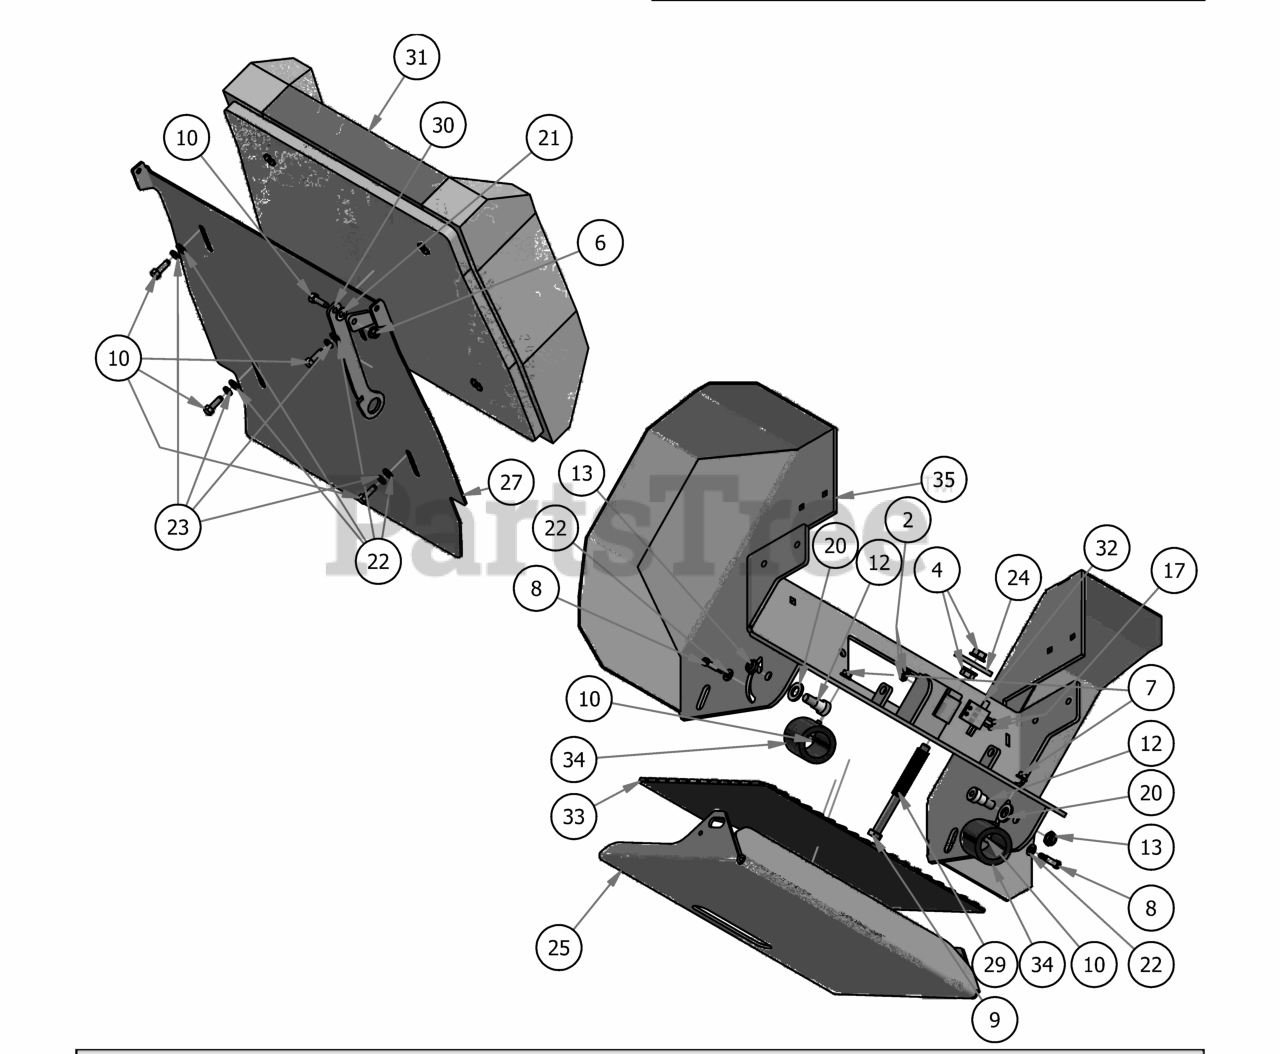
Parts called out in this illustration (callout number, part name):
1	3326 Wellnut (1/4-20 x 5/18")
2	10-24 Nylon Insert Locknut Zinc Orange Nylon
3	3/8" Nylock Flange Nut
4	1/2" Flange Nut
5	3/8" Hex Nut
6	5/16" Nylon Flange Nut
7	5/16" Flange Nut
8	5/16" x 7/8" Socket Head Shoulder Bolt
9	1/2-13 x 6 UNC
10	5/16-18 x 1 GR 5 Hex Bolt Zinc
11	3/8"-16 x 2" Gr 5 Hex Bolt
12	5/8'' x 5/8'' Shoulder Bolt
13	1/2" Nylcock Nut (1/2 Jam)
14	5/16" x 1 1/4" Carriage Bolt
15	3/8" x 1 1/4" Hex Bolt
16	3/8" x 1 1/4" Carriage Bolt
17	10-24 X 5/8 BS Button Head Bolt
18	.390 x .750 x .062 Nylon Washer
19	3/8" Lock Washer
20	.630 ID Plastic Washer
21	.360 ID Plastic Washer
22	5/16" Flat Washer
23	5/16" Lock Washer
24	MZ Deck Idler Spacer
25	2019 Stand-On Platform
26	2019 Stand On Access Panel
27	2019 Stand On Pad Plate Weldment
28	1/4"-20 x 3/4" Knurled Thumb Screw
29	Rider Presence Spring 9657K145
30	2019 Stand On Operator Pad Kickstand
31	2019 Stand-On Platform Pad
32	safety Switch
33	2019 Stand On Mat
34	GBR-647 Miner Elastomer
35	2019 Stand On Platform Support weldment
